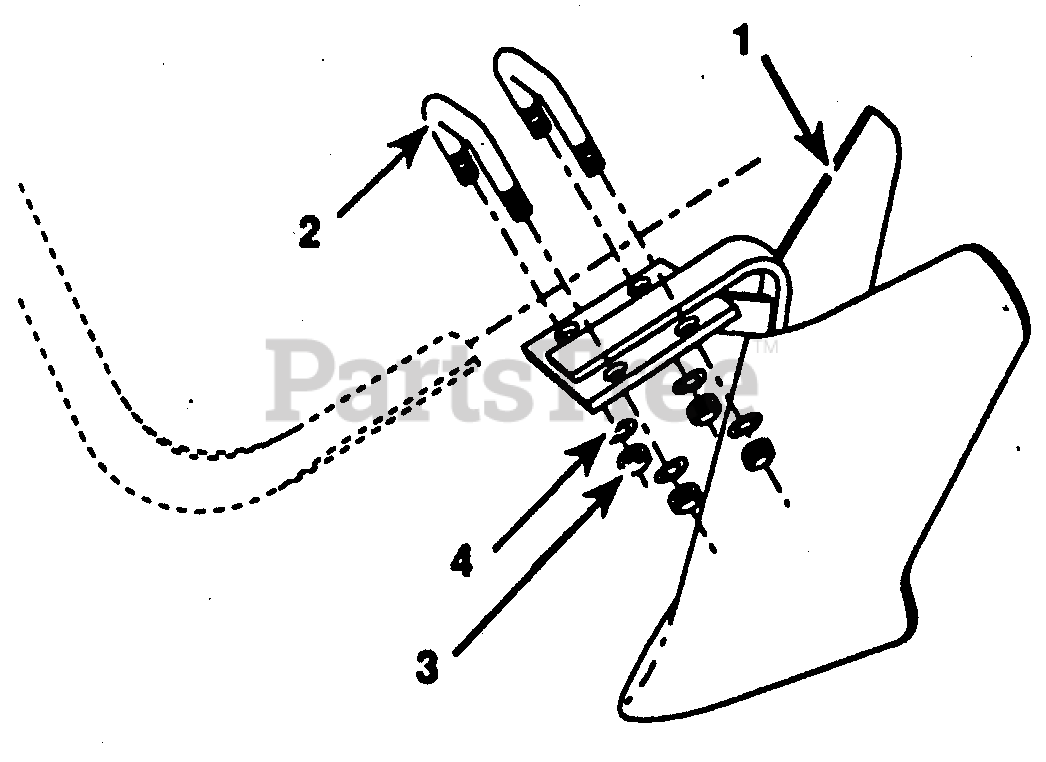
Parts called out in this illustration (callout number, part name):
1	Furrower Assembly
3	Nut, Hex 3/8-16 UNC
4	Lockwasher 3/8
